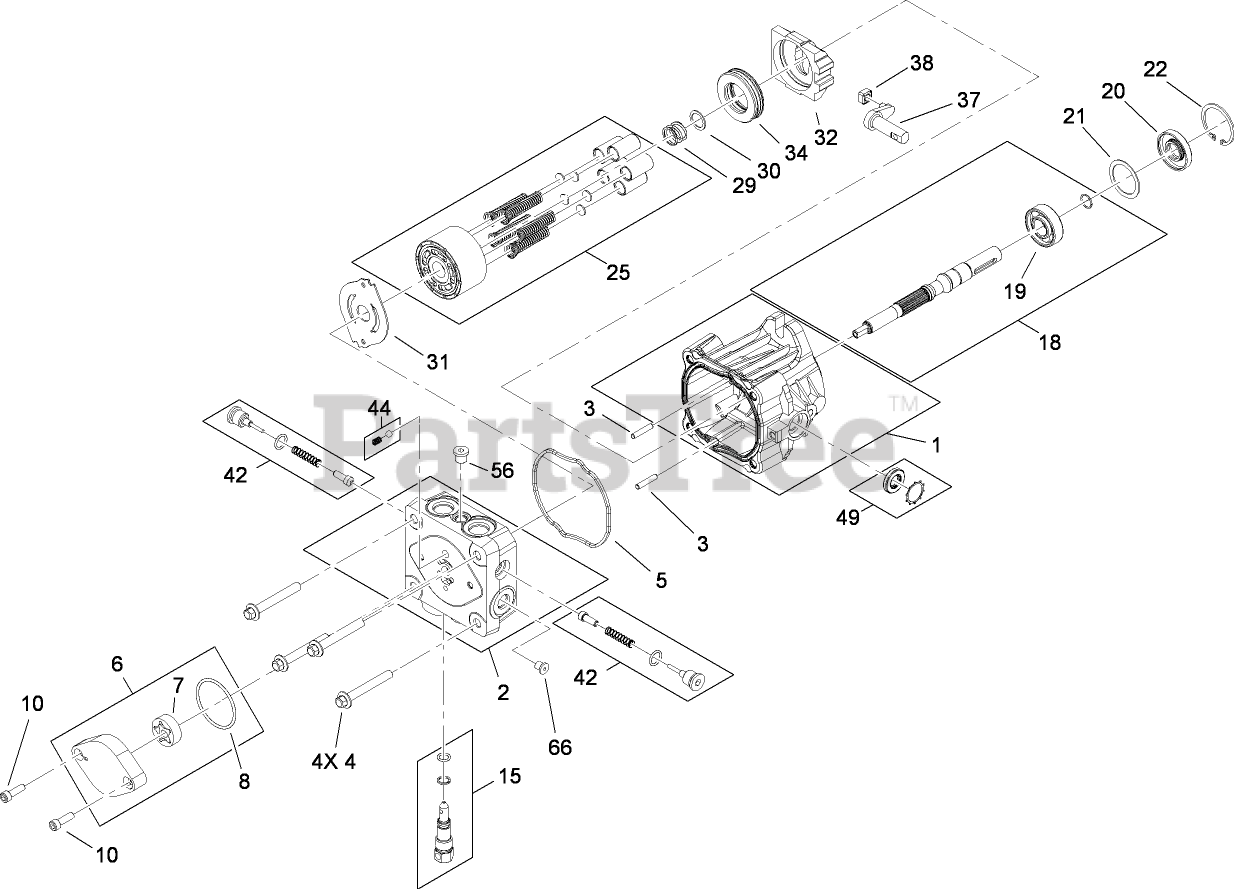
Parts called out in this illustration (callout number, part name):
1	HOUSING KIT
2	END CAP KIT (W/POPPETS)
3	PIN-HEADLESS, STRAIGHT
4	BOLT-HF
5	O-RING
6	CHARGE PUMP KIT
7	GEROTOR ASM
8	O-RING
10	SCREW-HSH
15	BYPASS VALVE KIT
18	INPUT SHAFT KIT
19	BEARING-BALL
20	SEAL-LIP
21	SPACER
22	RING-RETAINING
25	CYLINDER BLOCK KIT
29	SPRING-BLOCK
30	WASHER-THRUST
31	Plate-Valve
32	SWASHPLATE-VARIABLE
34	BEARING-THRUST
37	ARM-TRUNION
38	GUIDE-SLOT
42	VALVE-CHECK (W/POPPET)
44	CHARGE RELIEF VALVE KIT
49	TRUNNION SEAL / RETAINER KIT
56	PLUG-HSH
66	PLUG-HSH
